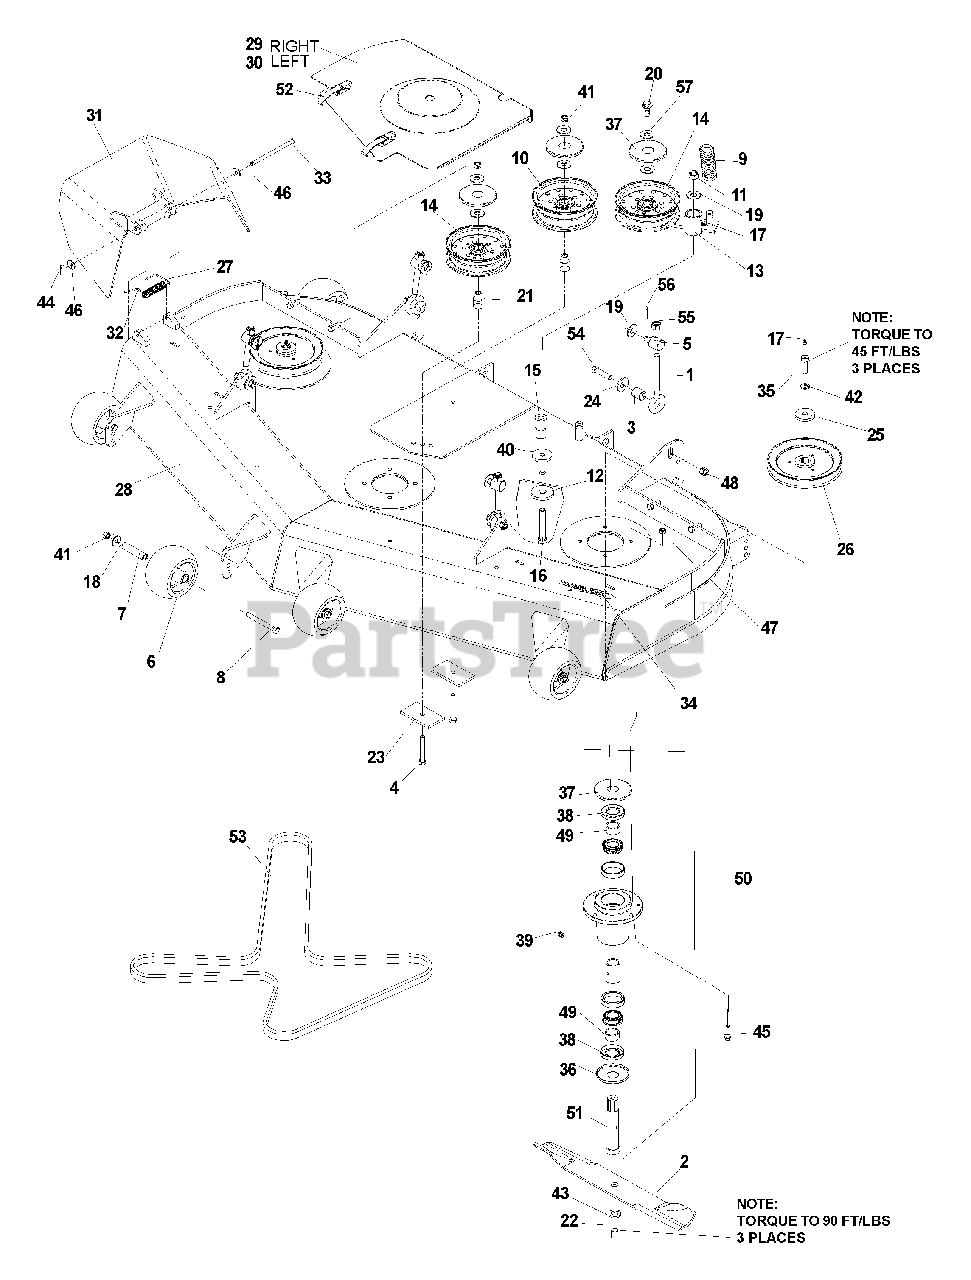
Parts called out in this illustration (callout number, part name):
2	BLADE, 21"
4	HCS, 3/8-16 X 2 3/4, GR5
6	ROLLER, ANTI SCALP
8	HCS, 3/8-16 X 3 1/2, GR8
9	SPRING, EXTENSION
10	PULLEY, IDLER
11	NUT, 1/2-13, NYLOC
12	WASHER, .65
14	PULLEY, IDLER
15	BUSHING, PIVOT
16	HCS, 1/2-13 X 3 1/4, GR5
17	ZERK, STRAIGHT, 1/4-28
18	WASHER, 3/8
19	WASHER, 9/16
20	HCS, 3/8-16 X 1,GR5
21	BUSHING, IDLER
22	HCS, 5/8-18 X 1 1/4, GR5
23	PAD
24	SPRING WASHER, 1/2
25	WASHER, .469
26	PULLEY
27	CAP-SLEEVE
28	DECK W/DECALS
29	BELT SHIELD, RIGHT
30	BELT SHIELD, LEFT
31	DISCHARGE CHUTE
32	SPRING, TORSION
33	PIN-CLEVIS, 5/16 DIA. X 5.19
34	DECAL, TUNNELRAM
35	HCS, 7/16-20 X 1 1/2, GR8, SPEC
36	BOTTOM DUST CAP
37	TOP DUST CAP
38	SHAFT SEAL
39	PLUG, VENTED
40	WASHER, 1/2
41	NUT, 3/8-16, NYLOC
42	LOCKWASHER, 7/16
43	LOCKWASHER, 5/8
44	PIN COTTER, 1/8 X 3/4
45	HCS, 5/16-18 X 1 1/4, GR5
46	WASHER, 5/16
47	NUT, 5/16-18, NYLOC
48	NUT, 7/16-14, CENTERLOCK, GR A
49	TOP & BOTTOM SPACER
50	SPINDLE ASSEMBLY
52	DRAW LATCH
54	HCS, 7/16-14 X 1 3/4, GR5
55	NUT, 1/2-13, NYLOC
56	PIN COTTER, 1/8 X 1
57	WASHER, 3/8, SPEC
